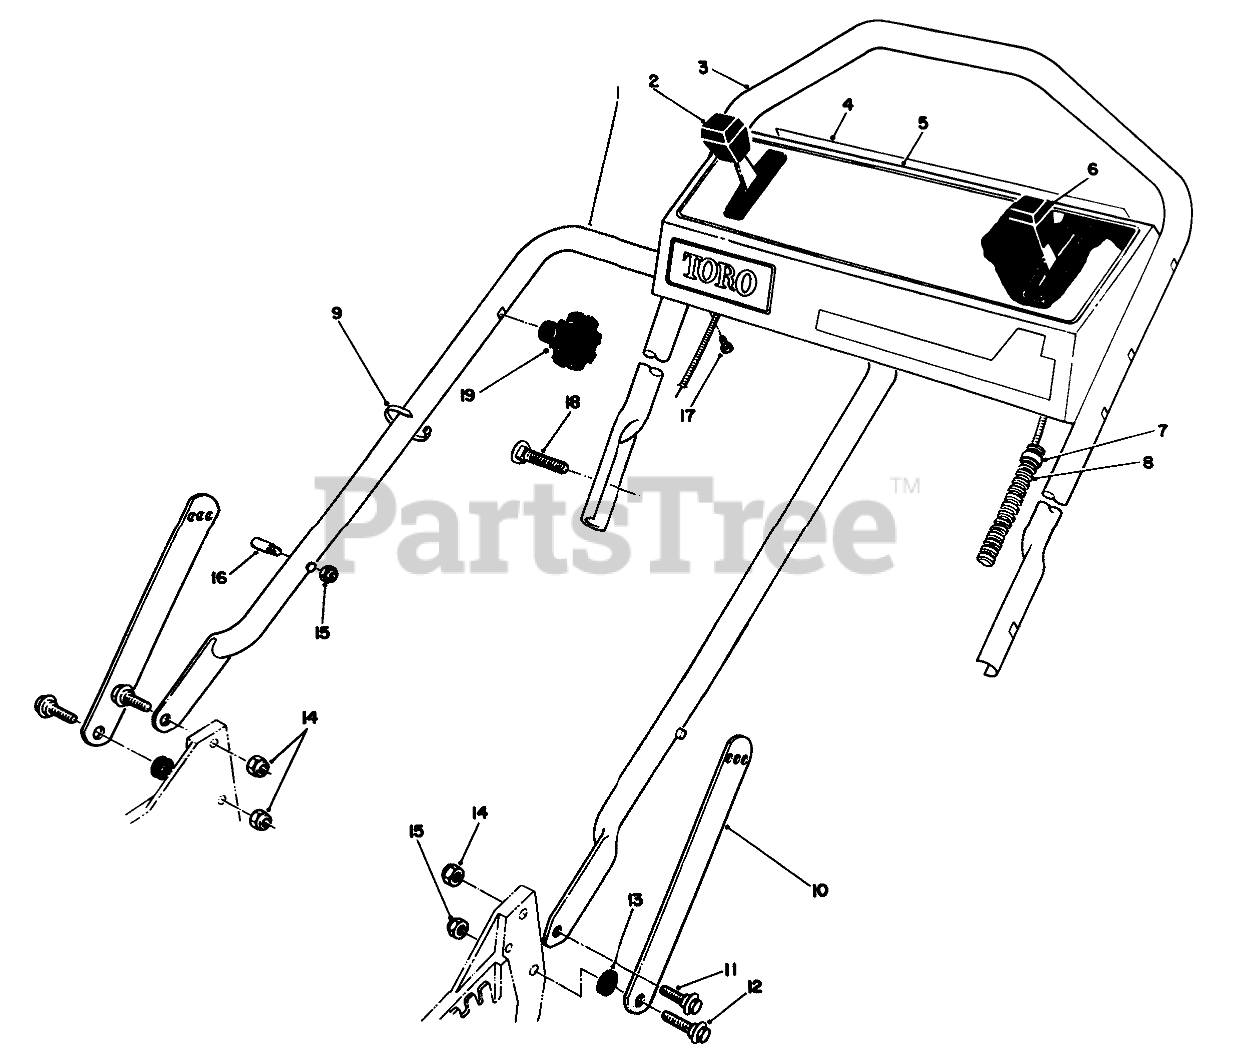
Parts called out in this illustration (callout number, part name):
1	LOWER HANDLE ASM
2	Control-Ground Speed
3	UPPER HANDLE
4	DECAL-PANEL, DANGER
5	Panel-Control
6	THROTTLE CONTROL
7	FITTING-RING
8	CONTROL CABLE COVER
9	TIE-CABLE
10	Handle Latch
11	SCREW-SHOULDER
12	SCREW-SHOULDER
13	SPACER
14	NUT-LOCK, NI
15	NUT-LOCK, NI
16	HANDLE PIN
17	SCREW-HWHTF
18	5/16-18 X 2 HNDLE SCREW
